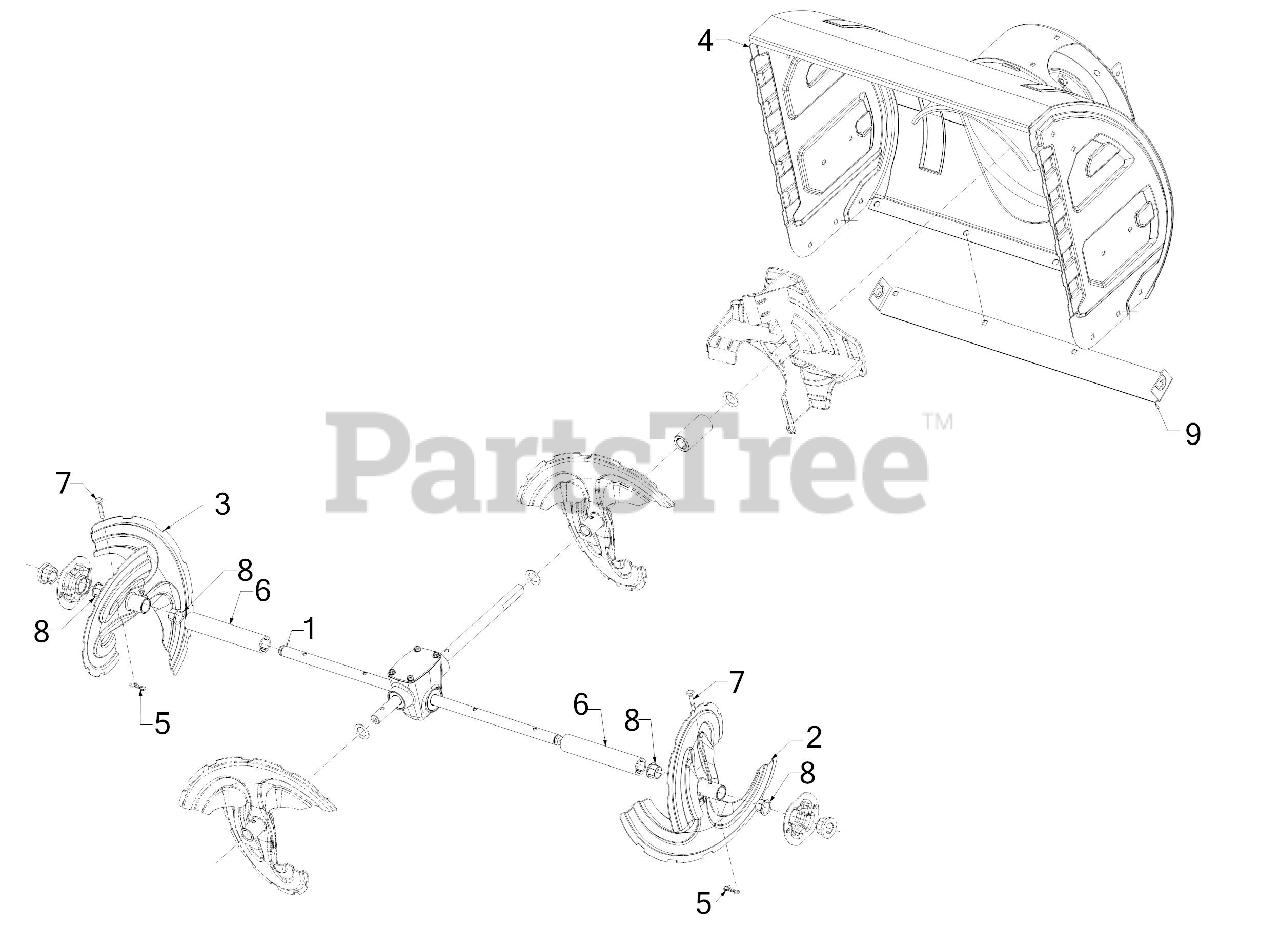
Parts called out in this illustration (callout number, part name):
1	26" AUGER GEARBOX ASSEMBLY
5	BOW TIE COTTER PIN 1/4-5/16
7	SHEAR PIN .25 x 1.50 GR2
8	FLANGE BUSHING
